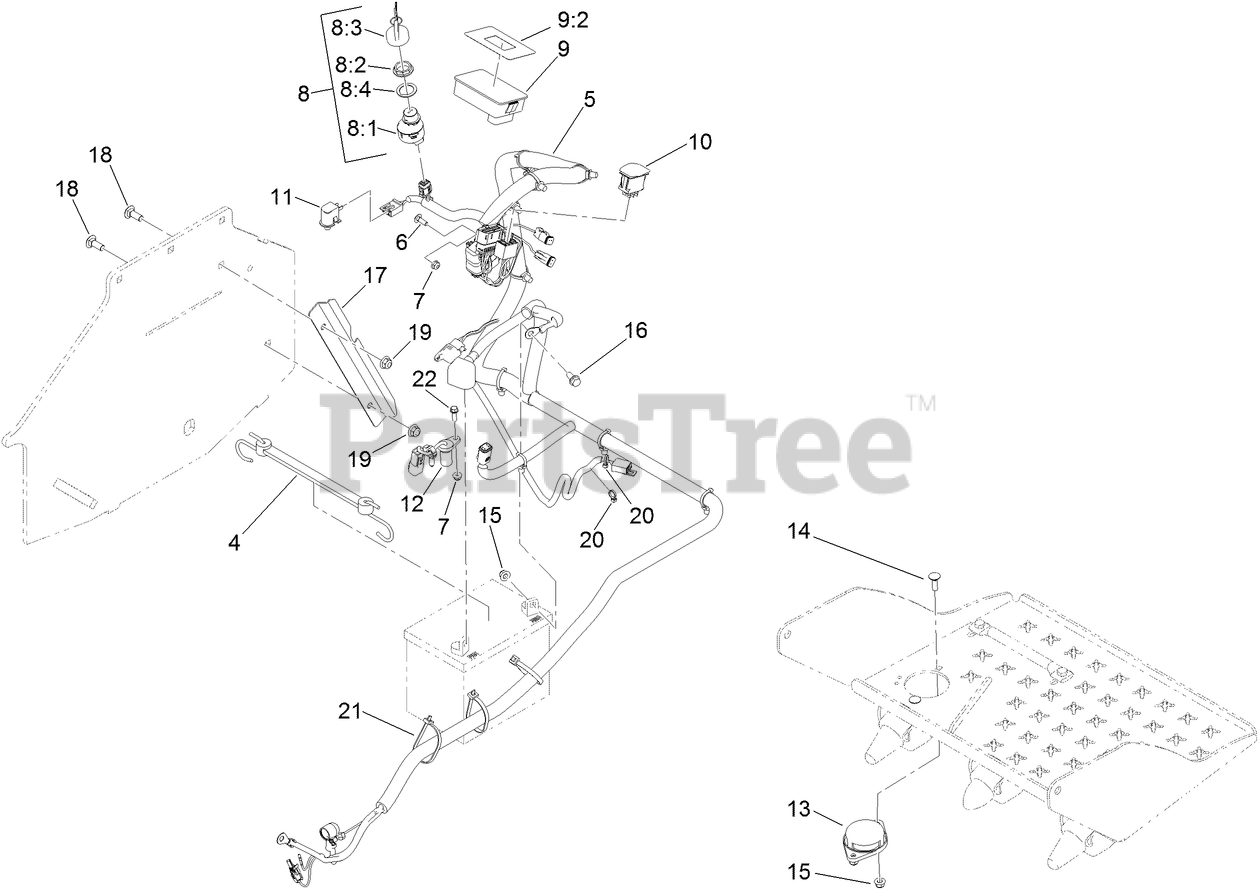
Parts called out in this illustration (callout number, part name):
4	HOLDDOWN-BATTERY
5	HARNESS-WIRE
6	BOLT-CARR
7	NUT-HF
8	IGNITION SWITCH ASM
8:1	SWITCH-IGNITION
8:2	NUT-MOUNTING
8:3	IGNITION KEY SET
8:4	WASHER-BACKUP
9	HOUR METER ASM
9:2	DECAL-METER, HOUR
10	SWITCH
11	SWITCH-BAIL
12	SENSOR-QUADRATURE
13	SWITCH-SEAT
14	BOLT-CARR
15	NUT-HF, NI
16	SCREW-HHF
17	GUARD-HARNESS
18	BOLT-CARR
19	NUT-HF, NI
20	TIE-CABLE
21	TIE-PLASTIC
22	SCREW-HWH
